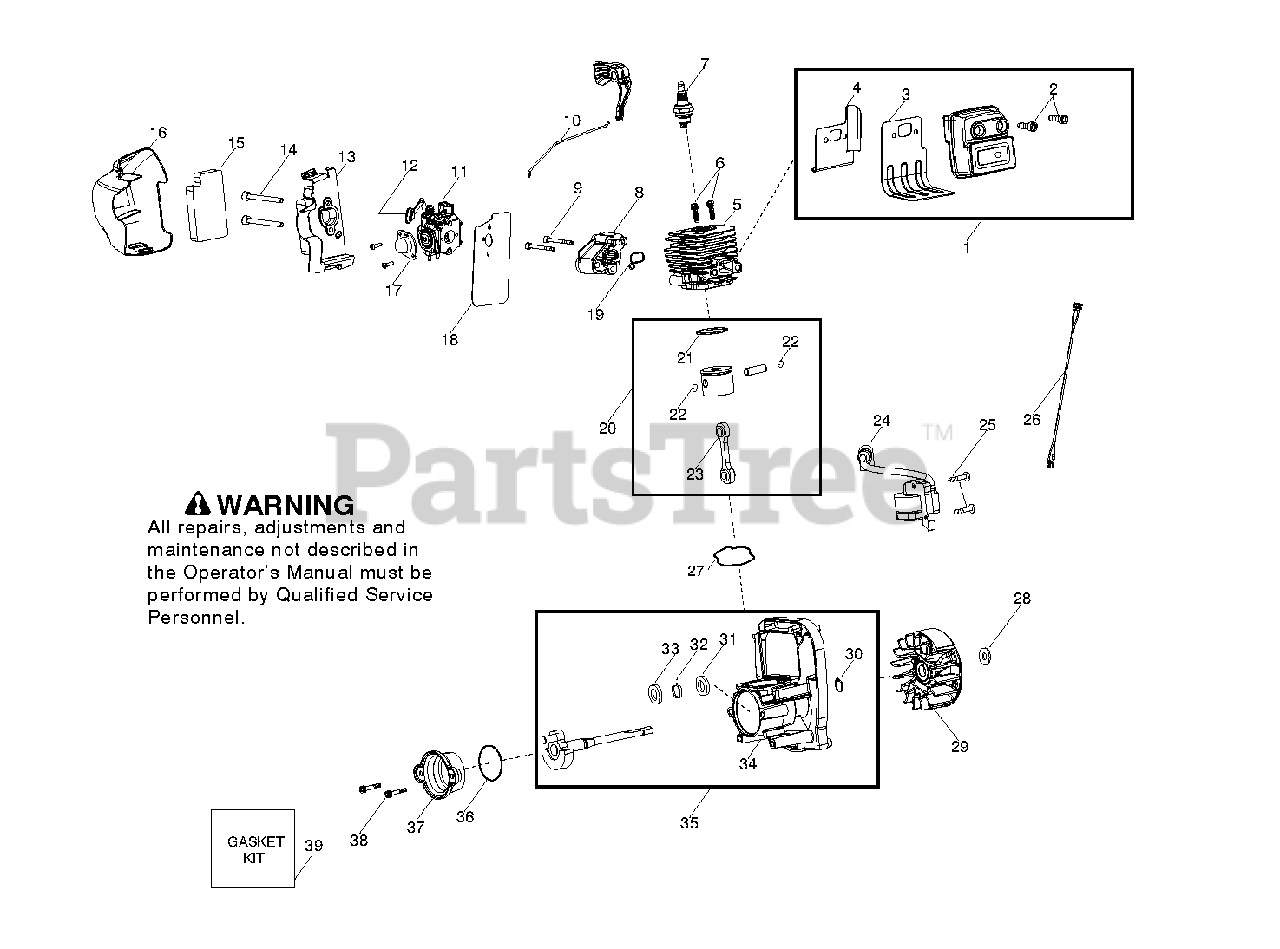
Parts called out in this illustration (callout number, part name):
1	ASSY MUFFLER WELDED
2	BOLT MUFFLER
4	SHIELD MUFFLER HEAT
5	CYLINDER CHROME 25CC
7	PLUG-SPARK (RCJ-6Y)
8	ADAPTER CARBURETOR
10	LINKAGE THROTTLE
11	KIT CARBURETOR WT-875A
12	LEVER CHOKE WT-875
13	BASE AIRBOX RED
15	AIR FILTER FOAM
16	COVER AIRBOX BLACK
17	PURGE BULB 188-16
20	KIT PISTON CONN ROD
21	PISTON RING
22	WRIST PIN RET.
23	KIT PISTON CONN ROD FORGED
24	KIT MODULE W/0 INTERRUPT
26	HARNESS WIRE
28	WASHER FLAT
29	FLYWHEEL
30	RETAINING RING
31	OUTER BEARING
33	BEARING
34	ASSY CRANKCASE
35	KIT CRANKCASE/CRANKSHAFT
37	ASSY REAR PLUG
39	KIT GASKET 25CC
